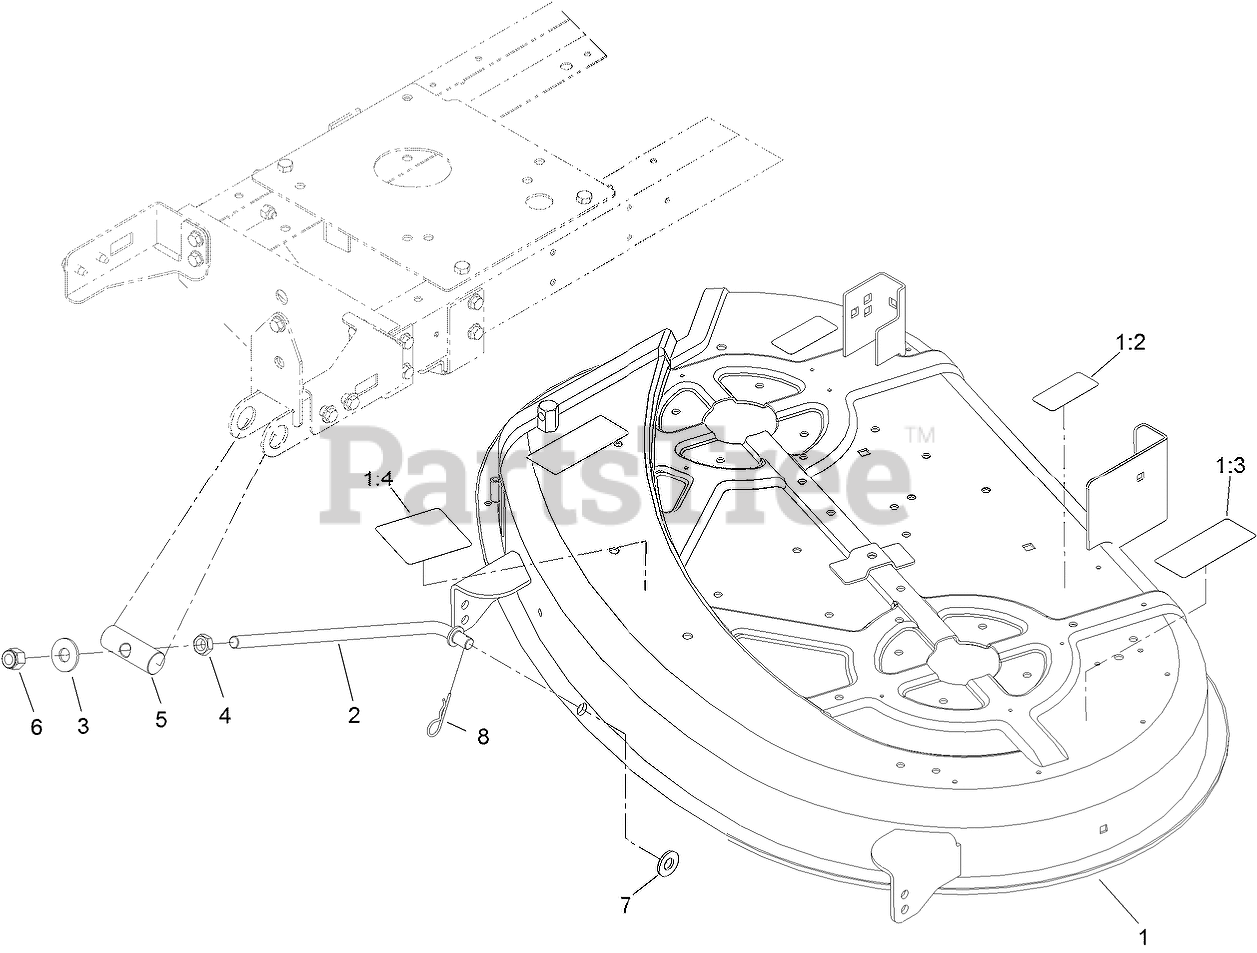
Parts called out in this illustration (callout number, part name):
1	DECK-ASSEMBLY, 38 INCH
1:2	DECAL-WARNING
1:3	DECAL-WARNING
1:4	DECAL-GUIDE, BELT
2	ROD-PIVOT
3	WASHER-FLAT
4	NUT-JAM
5	PIN-PIVOT
6	NUT-HEX
7	WASHER-THRUST
8	PIN-HAIR
